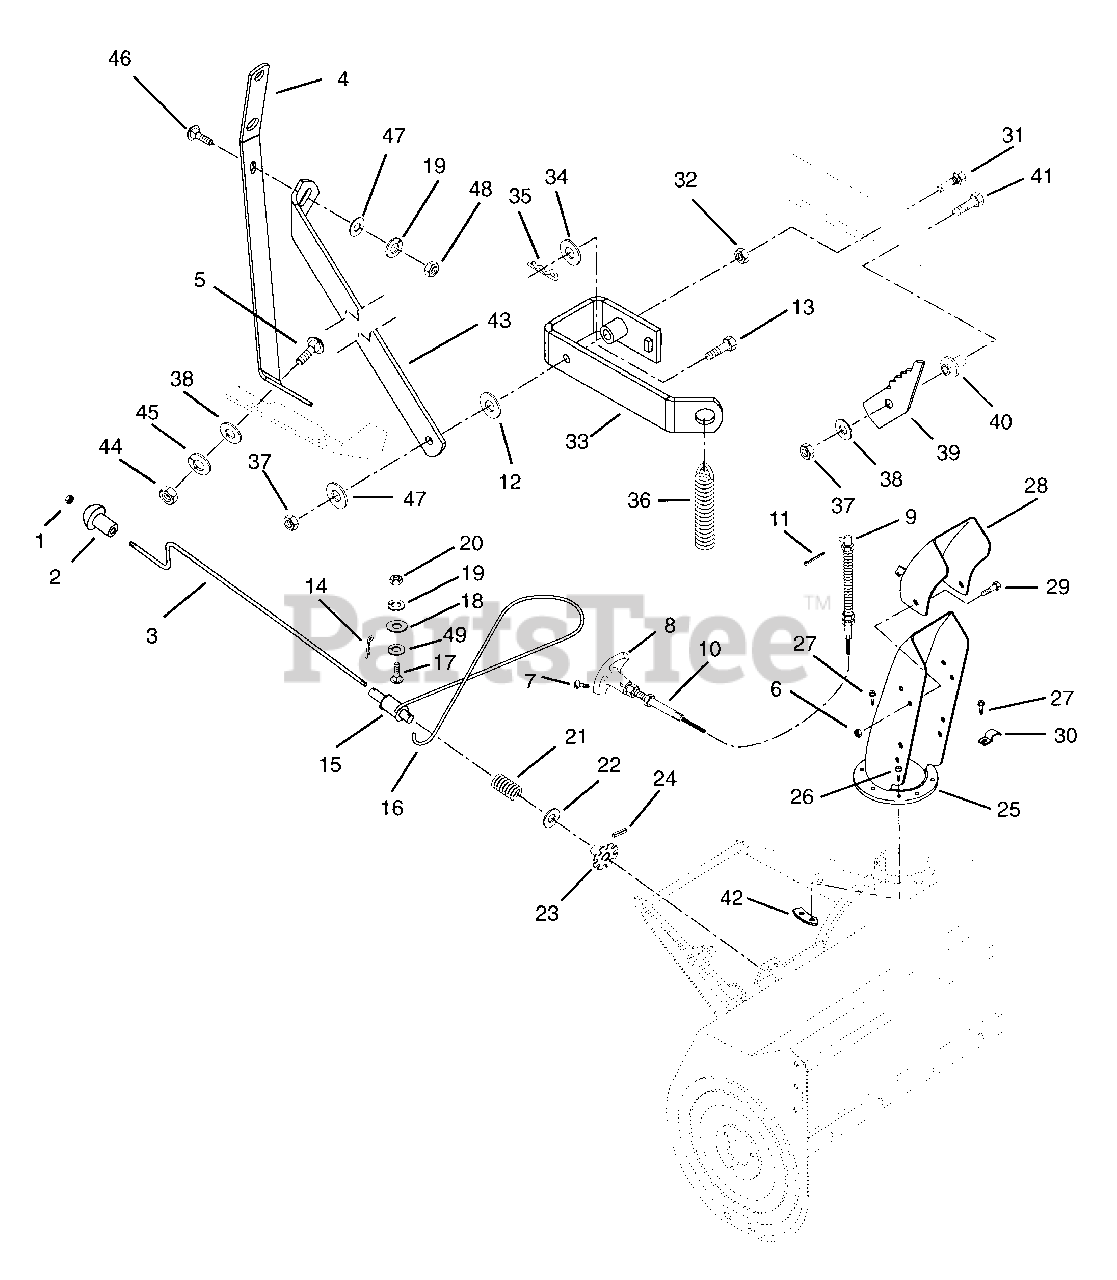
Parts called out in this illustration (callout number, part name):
1	@NUT-LK-CTR-JAM .375-16 YWZC
3	CHUTE CONTROL CRANK
4	SUPPORT, ROD
5	@BLT-RDHDSQNK .38-16X1.00 G2YZ
6	@NUT-LK-CTR .38-16 YWZC
7	@SCR-MCH 8-32X.75 HWH YWZC
8	KNOB-BLACK
10	CONTROL CABLE
11	@PIN-CTR .09X.75 EXTPRSQCT YWZ
12	@WSHR-FL-STL.38X.875X.083 YWZC
13	BLT-HEX .31-18X1.00 PL GR5
14	PIN-HAIR INT .08X.38X1.42 YWZC
15	SPOOL
17	@BLT-RDHDSQNK .25-20X.75 G5YZ
18	@WSHR-FL-STL.281X.62X.065 YWZC
19	@WSHR-LK-EXT.262X.502X.026YWZC
20	@NUT-HEX .25-20 YWZC
21	SG-COMP .054X.75X1.6
22	@WSHR-FL-STL.656X1.31X.095 YWZ
23	DISC ASSEMBLY
24	PIN-ROLL .188X1.00
25	DISCHARGE CHUTE
26	SCR-TAP 12-24X.50 TORX YWZC TR
27	SCR-TAP 12-24X.75 HWH PL TR
28	DEFLECTOR W/DECAL
29	@BLT-HEX .38-16X.75 GR5 YWZC
30	CABLE CLAMP
31	STUD-WEIGHT
32	@NUT-LK-CTR .50-13 YWZC
33	SPRING ARM
34	NUT-HEX-JAM .375-16 YWZC
35	PIN-HAIR INT .08X.18X1.18 YWZC
36	SG-TENS .188X1.50X8.5 WLD 57
37	@NUT-LK-CTR .31-18 YWZC
38	@WSHR-FL-STL.38X.875X.083 YWZC
39	SPRING ASSIST CONTROL
40	SPACER .323X.498X.531X1.000
41	@BLT-HEX .31-18X1.25 GR5 YWZC
42	CHUTE CLAMP
43	BRACE
44	NUT-HEX .375-16
45	@WSHR-LK .38X.094 REG YWZC
46	@BLT-RDHDSQNK .31-18X1.00 G5YZ
47	@WSHR-FL-STL.344X.688X.065YWZC
48	@NUT-HEX .31-18 YWZC
49	WSHR-LK PYM .31X.062YWZC
